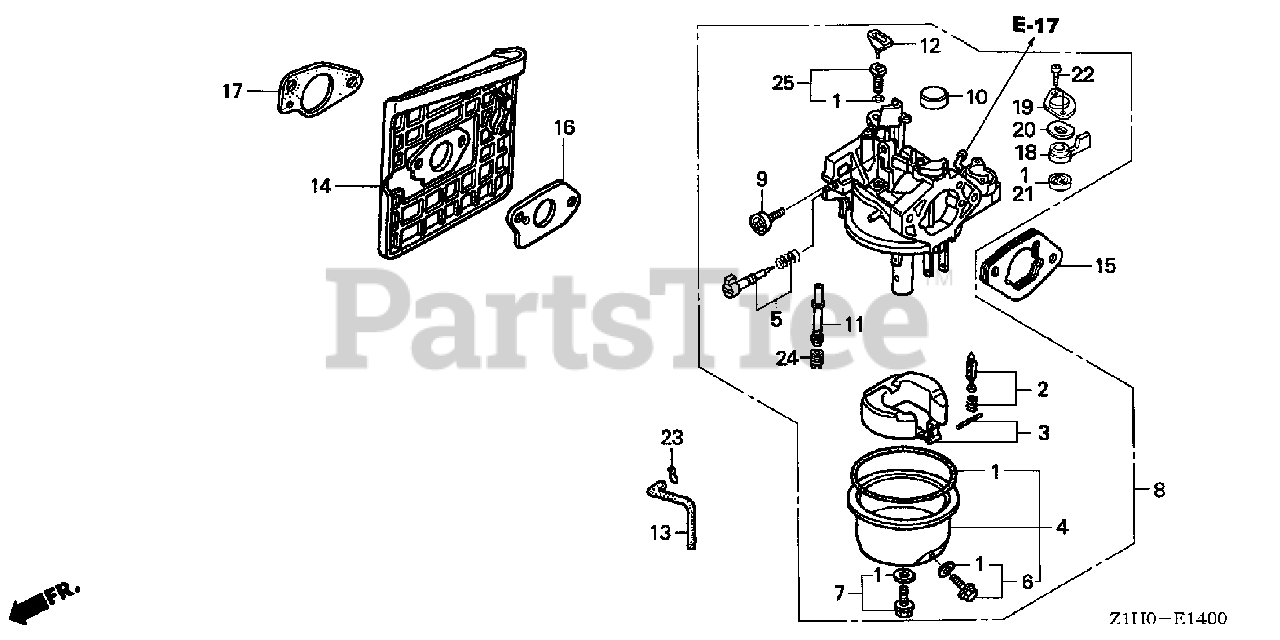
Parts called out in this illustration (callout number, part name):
1	GASKET SET (EXC. 16173-001-004) (EXCEPT 16173-001-004)
2	VALVE SET, FLOAT
4	CHAMBER SET, FLOAT
5	SCREW SET, PILOT
6	SCREW SET, DRAIN
7	SCREW SET
8	CARBURETOR ASSY. (BE81H A)
9	SCREW, THROTTLE STOP
10	CAP, CHOKE DUST
11	NOZZLE, MAIN
12	COLLAR, SETTING
13	TUBE, AIR VENT (75MM)
14	INSULATOR, CARBURETOR
15	SPACER, CARBURETOR
16	GASKET, CARBURETOR
17	GASKET, INSULATOR
18	LEVER, PETCOCK
19	PLATE, LEVER SETTING
20	SPRING, PETCOCK LEVER
21	GASKET, PETCOCK
22	SCREW, PAN (3X6)
23	CLIP, TUBE (B8)
24	JET, MAIN (#88)
24	JET, MAIN (#90)
24	JET, MAIN (#92)
25	JET SET, PILOT (#38)
